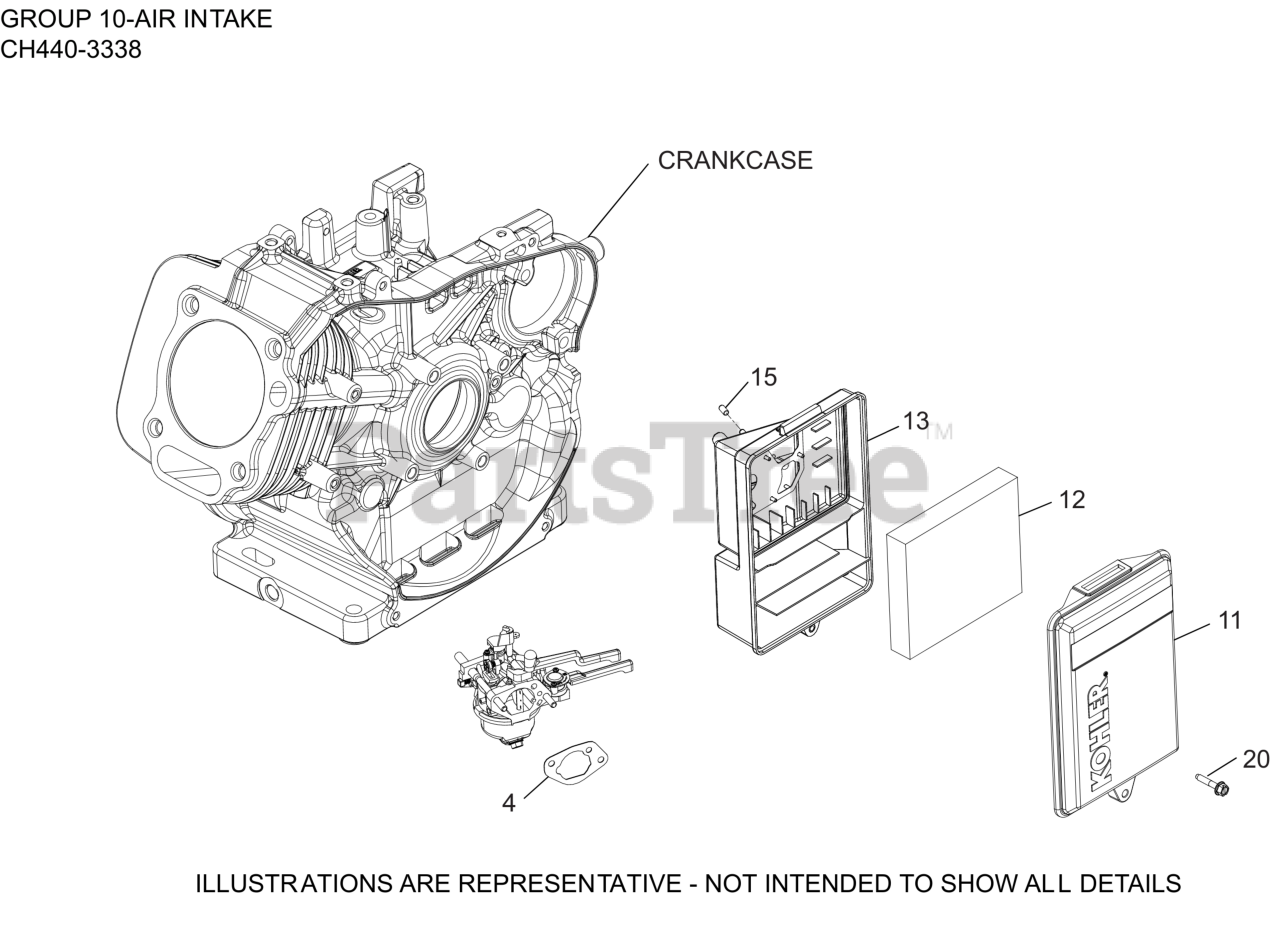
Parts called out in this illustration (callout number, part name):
4	GASKET, AIR CLEANER
11	COVER, AIR CLEANER
12	ELEMENT, AIR FILTER
13	BASE ASSEMBLY, AIR CLEANER
15	CAP, MASKING (CKY)
20	SCREW, HEX FLANGE SLOTTED (M6)
